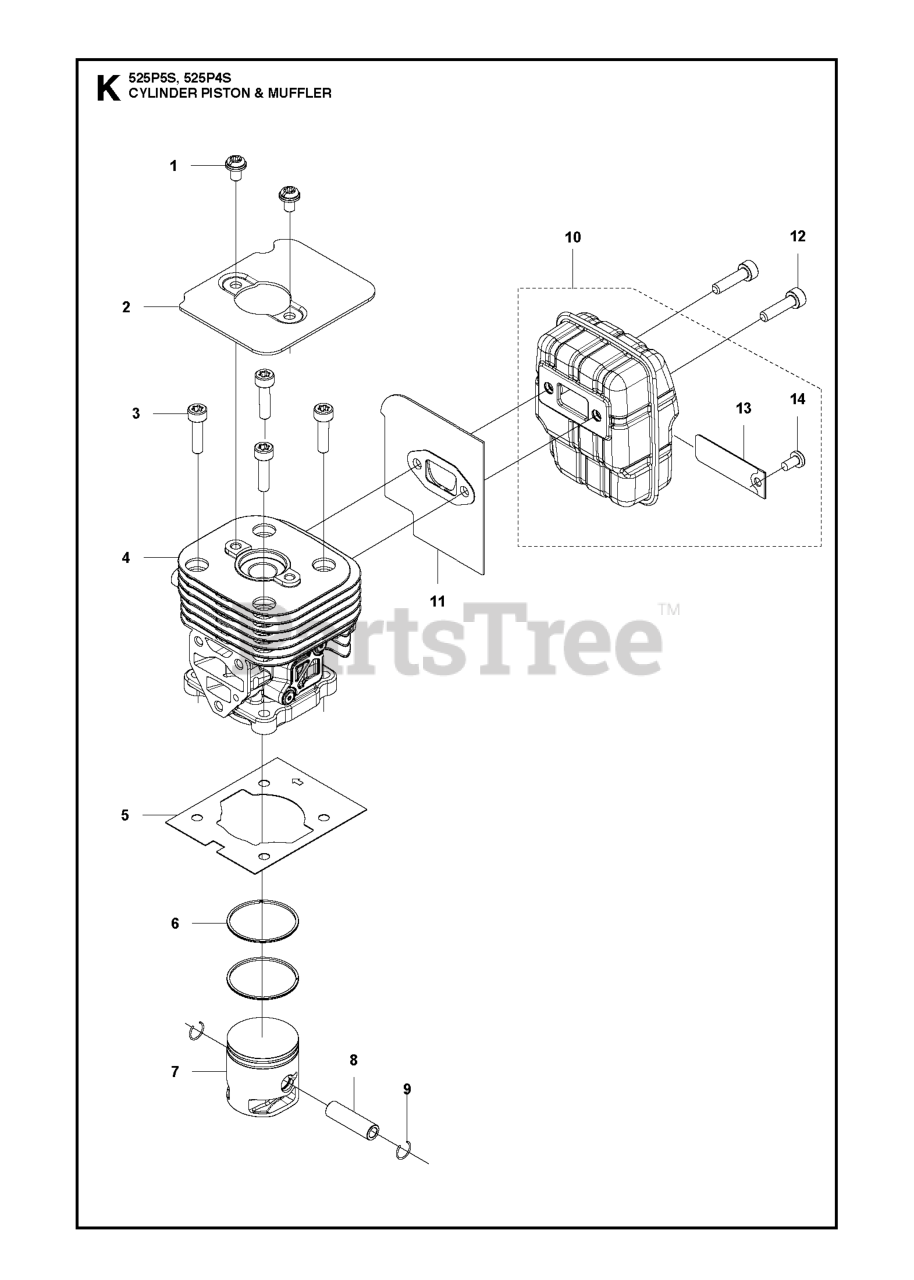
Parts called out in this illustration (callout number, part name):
2	PLATE CYLINDER
3	BOLT
4	CYLINDER COMP
5	GASKET BASE
10	Mufflers
10	MUFFLER ASSY
11	GASKET MUFFLER
12	BOLT
13	SPARK ARRESTER
14	SCREW CRPANT TYPE F ST4.2X9.5
